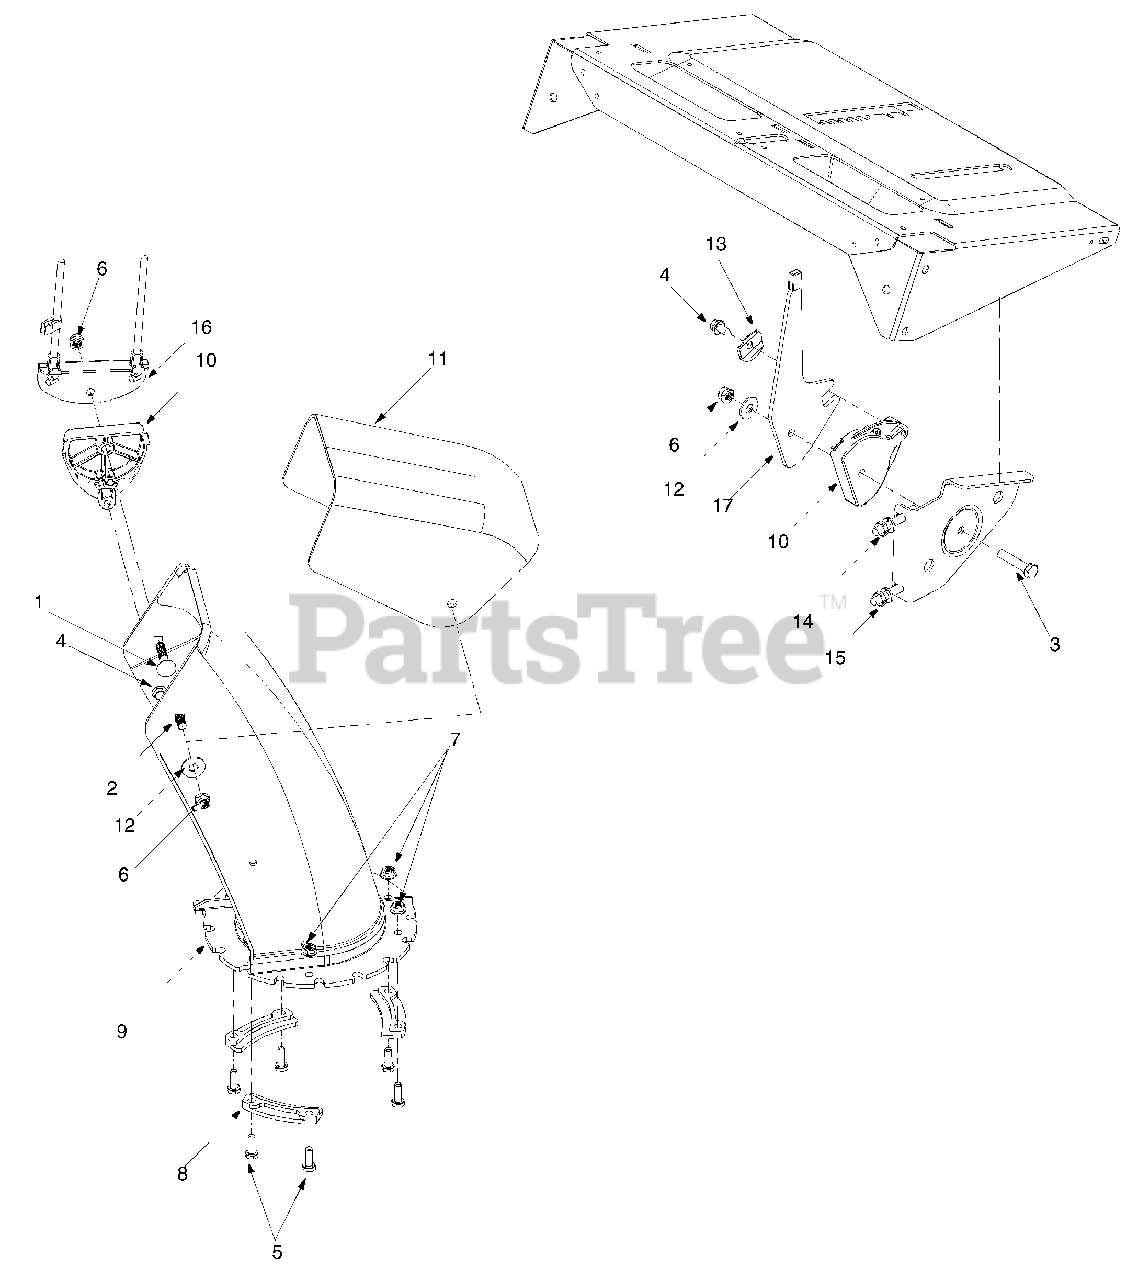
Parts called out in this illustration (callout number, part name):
1	Carriage Bolt: 5/16-18 x 1.5"
2	Carriage Bolt: 5/16-18 x 0.75"
3	Hex Bolt: 5/16-18 x 1.5 Gr. 5
4	Hex Washer Head AB Screw: 1/4-14 x 0.625"
5	Hex Bolt: 1/4-20 x 0.75"
6	Hex Lock Nut: 5/16-18
7	Flange Lock Nut
8	Chute Flange Keeper
9	Lower Chute
10	Chute Tilt Cable Guide
11	Upper Chute
12	5/16 Washer
13	Special Washer
14	Control Cable: Chute Deflector
15	Chute Deflector Cable w/Clip
